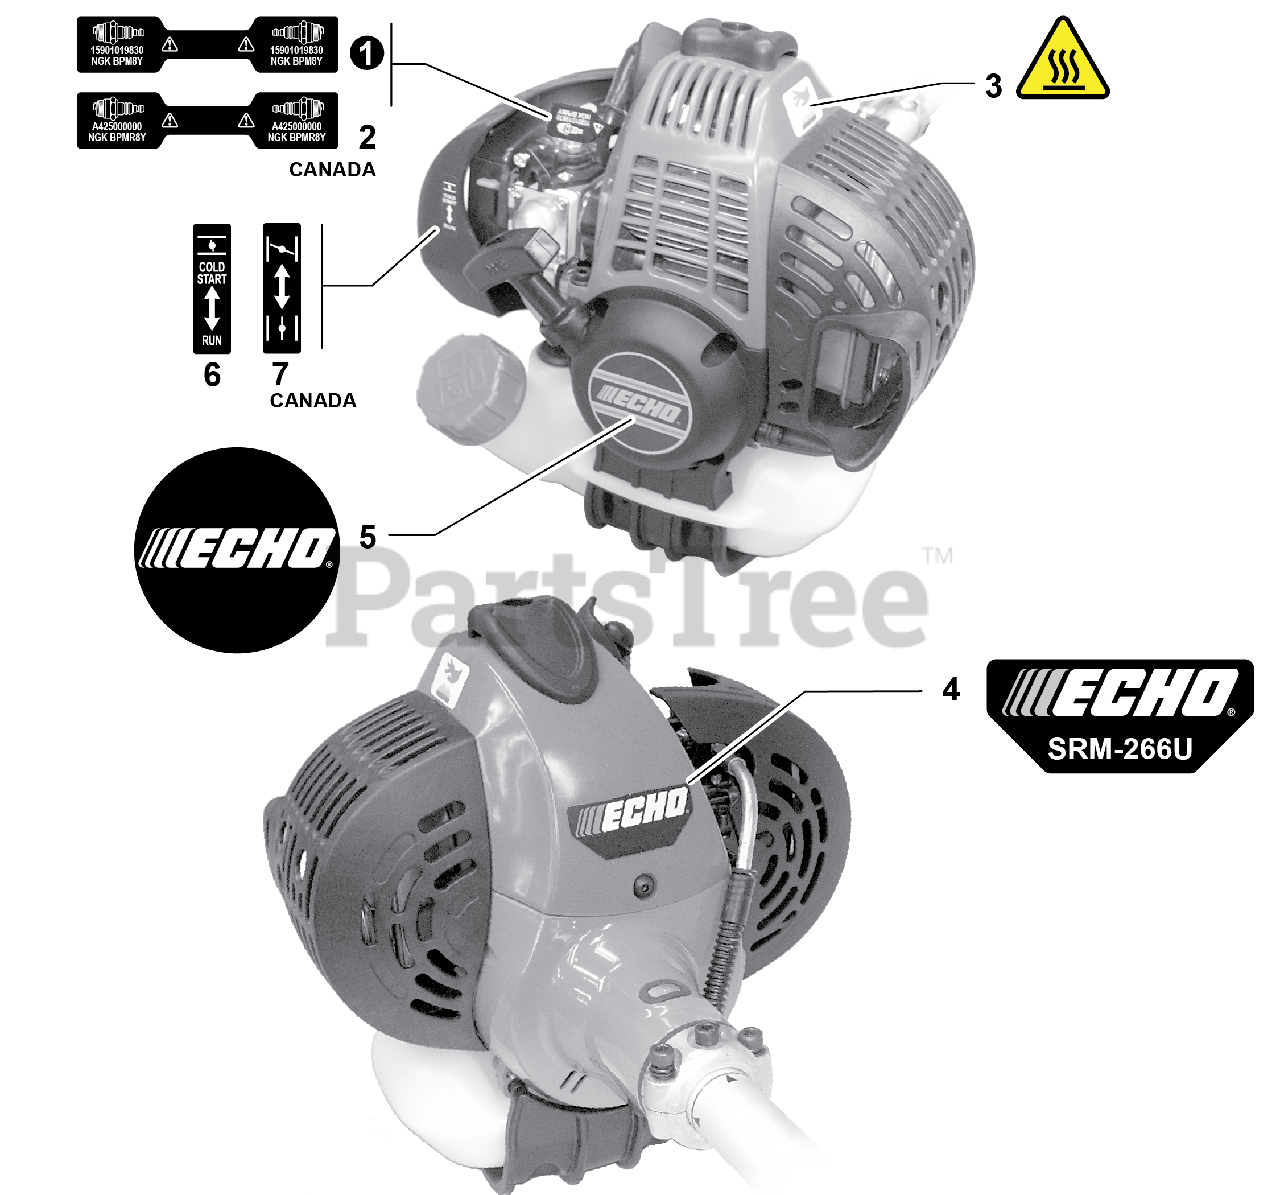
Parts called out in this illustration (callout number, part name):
1	LABEL, SPARK PLUG - BPM8Y
2	LABEL, SPARK PLUG - BPMR8Y
3	LABEL, CAUTION - HOT
4	LABEL - MODEL SRM-266U
5	LABEL, ECHO
6	LABEL, CHOKE
7	LABEL, CHOKE
